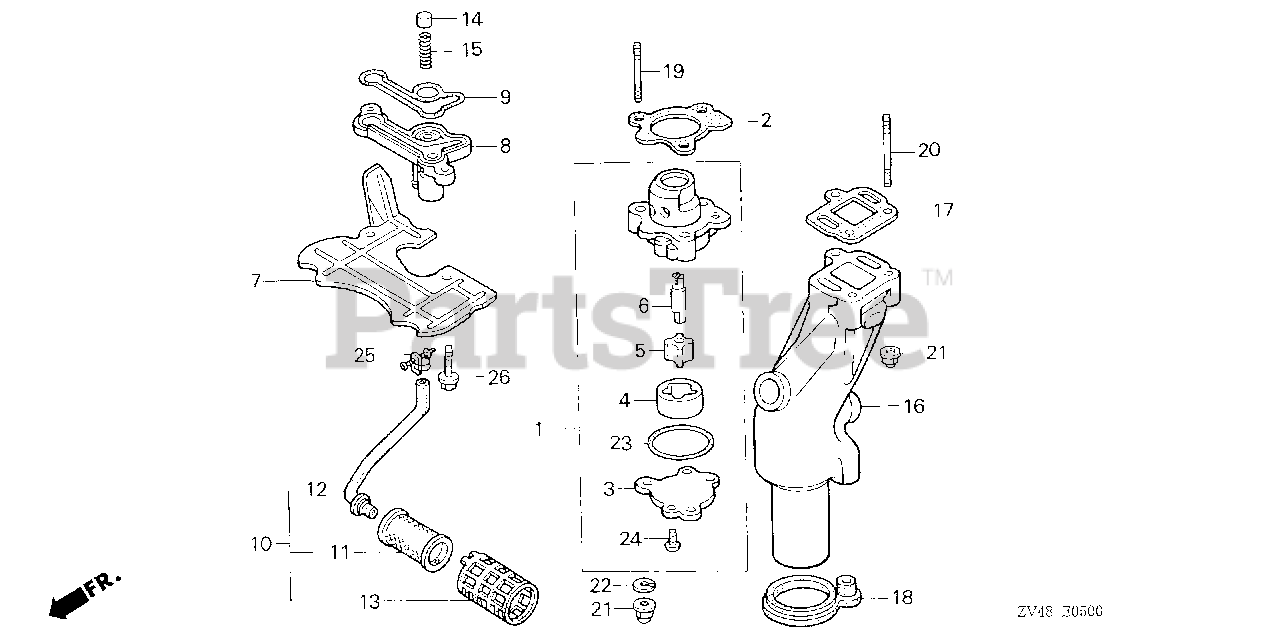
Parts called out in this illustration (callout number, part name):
1	PUMP ASSY., OIL
2	GASKET, PUMP BODY
3	COVER, OIL PUMP
4	ROTOR, OIL PUMP (OUTER)
5	ROTOR, OIL PUMP (INNER)
6	SHAFT, OIL PUMP
7	PLATE, DEFENSE
8	FLANGE, OIL FILTER
9	GASKET, OIL FILTER
10	FILTER ASSY., OIL
11	FILTER, OIL
13	HOLDER, OIL FILTER
14	VALVE, CHECK
15	SPRING, CHECK VALVE
16	PIPE, EX. *TBLACK* (BLACK)
17	GASKET, EX. PIPE
18	GROMMET, WATER TUBE
19	BOLT, STUD (6X39)
20	BOLT, STUD (6X42)
21	NUT, CAP (6MM)
22	WASHER, SPRING (6MM)
23	O-RING, PUMP COVER
24	SCREW, PAN (5X8)
25	CLAMP, TUBE (D10.5)
26	BOLT, FLANGE (6X22)
